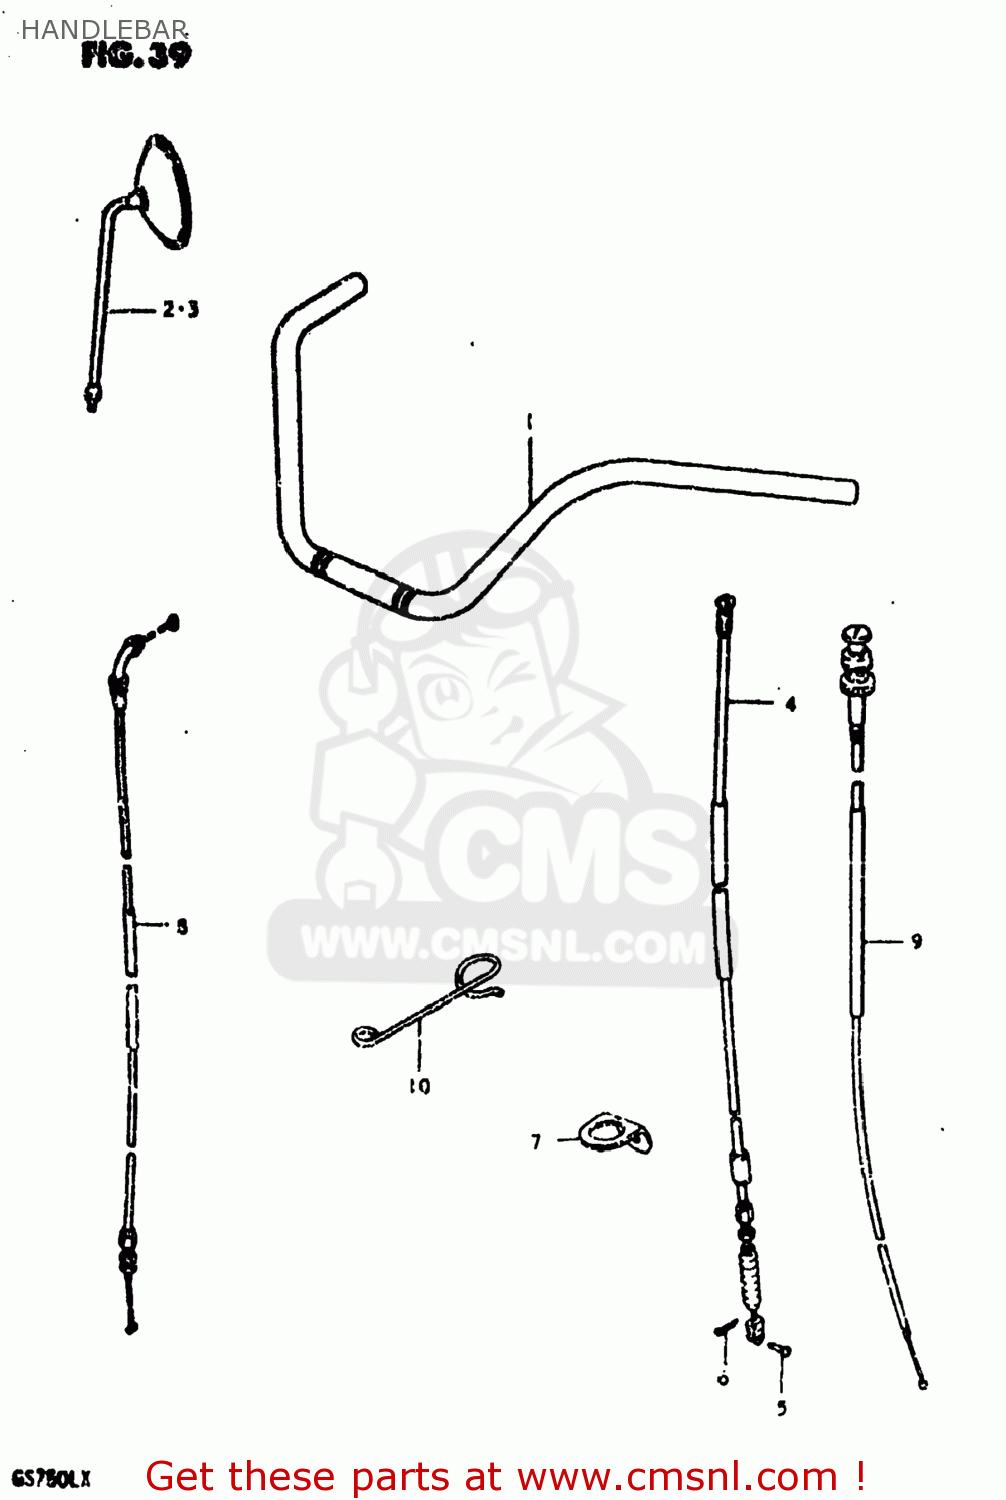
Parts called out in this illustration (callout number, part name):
1	HANDLEBAR
2	MIRROR ASSEMBLY,RIGHT
3	MIRROR ASSEMBLY,LEFT
4	CABLE,CLUTCH
5	PIN(L:15)
6	PIN
7	GUIDE,BRAKE HOSE
8	CABLE ASSEMBLY,THROTTLE
9	CABLE ASSEMBLY,STARTER
10	GUIDE,CLUTCH CABLE
